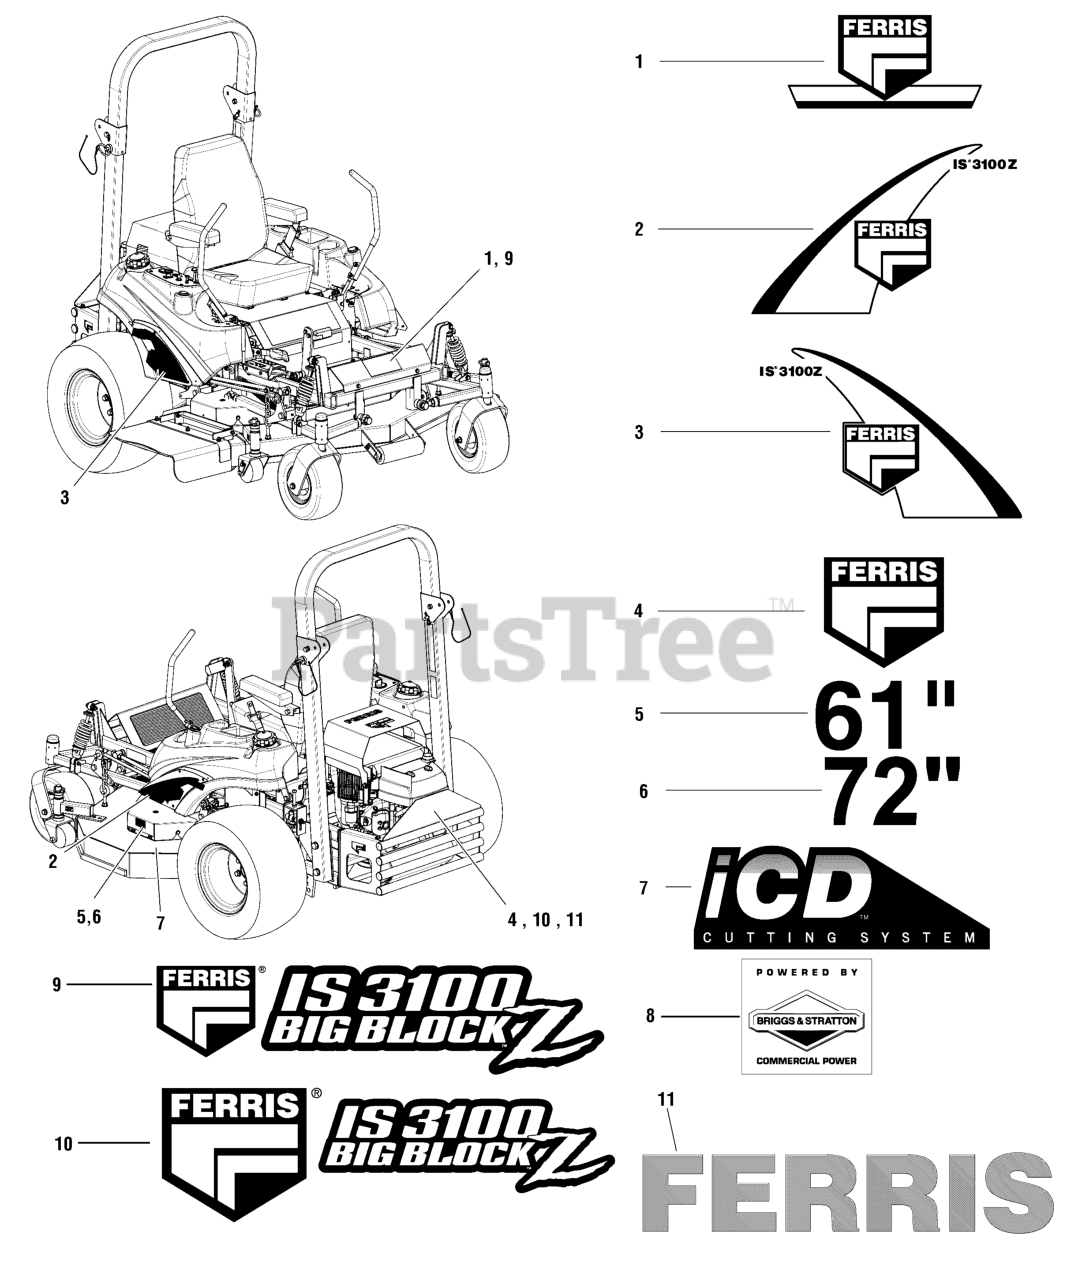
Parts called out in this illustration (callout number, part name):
1	DECAL, FERRIS, FRONT, 7.25 X 3.50
2	DECAL, BADGE, IS3100Z, LH
3	DECAL, BADGE, IS3100Z, RH
5	DECAL, 61
6	DECAL, 72
7	DECAL, iCD CUTTING SYSTEM
9	DECAL, 3100, BIG BLOCK, FRONT
10	DECAL, 3100, BIG BLOCK, REAR
11	DECAL, FERRIS, 2.23" X 11.39"
